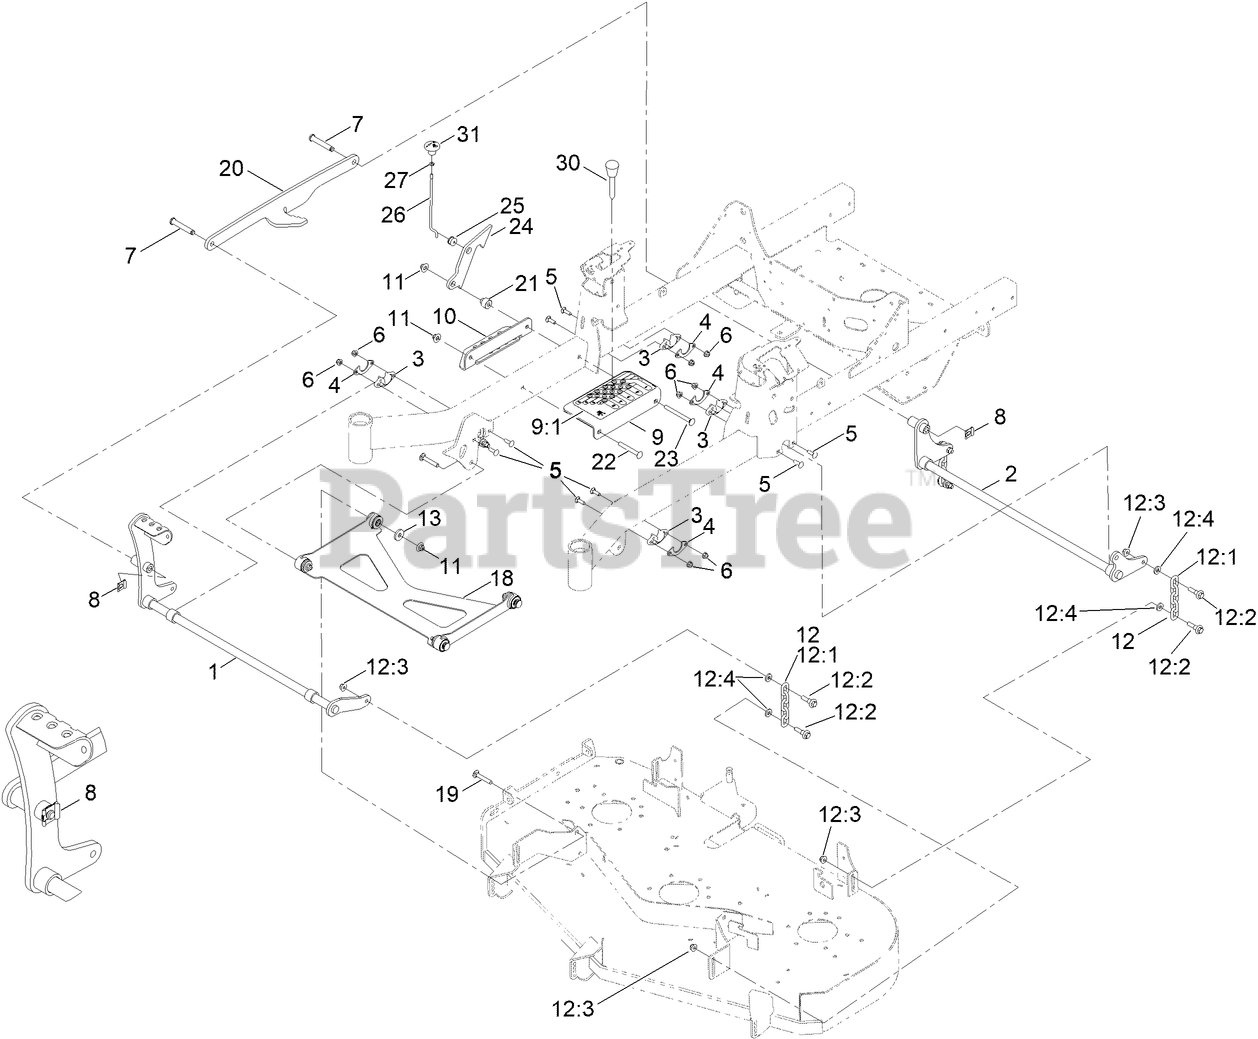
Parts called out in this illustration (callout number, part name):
1	SHAFT-LIFT, DECK
2	SHAFT-LIFT, DECK (REAR)
3	BEARING-FLANGE
4	GUSSET-LIFT, DECK
5	SCREW-CARR
6	NUT-HF, NI
7	PIN-CLEVIS
8	CLIP-PIN
9	BRACKET ASM
9:1	DECAL-HOC
10	ANGLE-HOC, LOWER
11	NUT-FLANGE, NI
12	DECK CHAIN ASM
12:1	CHAIN-LIFT, DECK
12:2	BOLT-SHOULDER
12:3	NUT-HF, NI
12:4	SPACER
13	WASHER
18	DECK STRUT ASM
19	SCREW-CARR
20	LINK-LIFT
21	SPACER-STEPPED
22	SCREW-CARR
23	SCREW-CARR
24	PLATE-LOCK, TRANSPORT
25	GROMMET
26	ROD-LOCK, TRANSPORT
27	NUT-JAM
30	PIN-HOC
